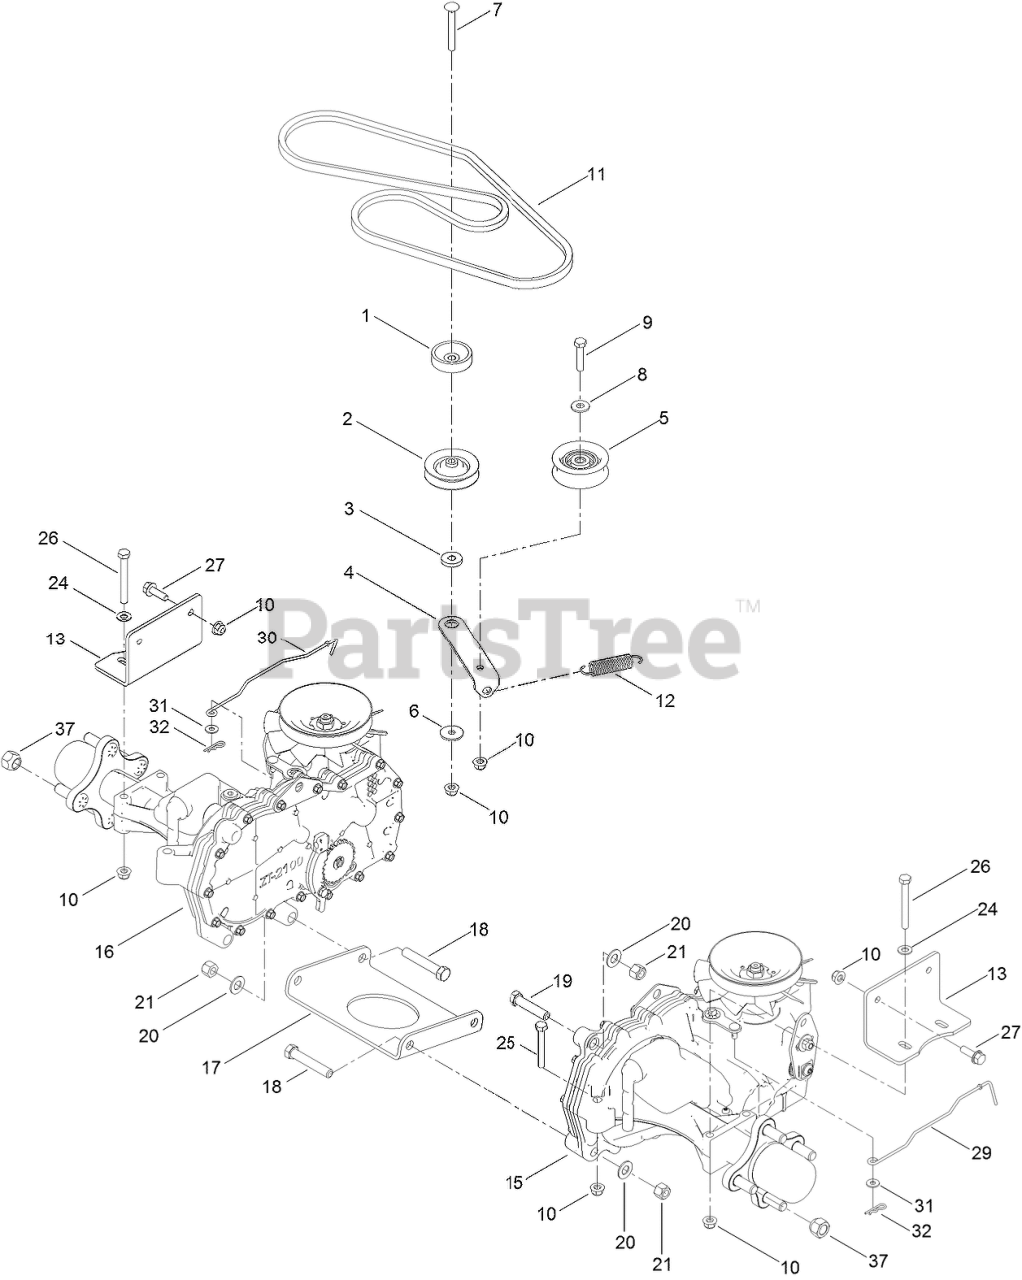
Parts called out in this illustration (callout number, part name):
1	SPACER
2	PULLEY-IDLER
3	SPACER-ARM, IDLER
4	ARM-IDLER
5	PULLEY-IDLER, FLAT
6	WASHER-PIVOT
7	SCREW-CARR
8	WASHER-FLAT
9	SCREW-HH
10	NUT-HF, NI
11	V-BELT
12	SPRING-PEDAL, RETURN
13	MOUNT-HYDRO
15	LH HYDRO TRANSAXLE ASM
16	RH HYDRO TRANSAXLE ASM
17	PLATE-CROSS, HYDRO
18	SCREW-HH
19	SCREW-HH
20	WASHER-FLAT
21	NUT-LOCK, NI
24	WASHER-PLAIN
25	SCREW-HH
26	SCREW-HH
27	SCREW-HHF
29	ROD-BYPASS, LH
30	ROD-BYPASS, RH
31	WASHER
37	NUT-LUG
